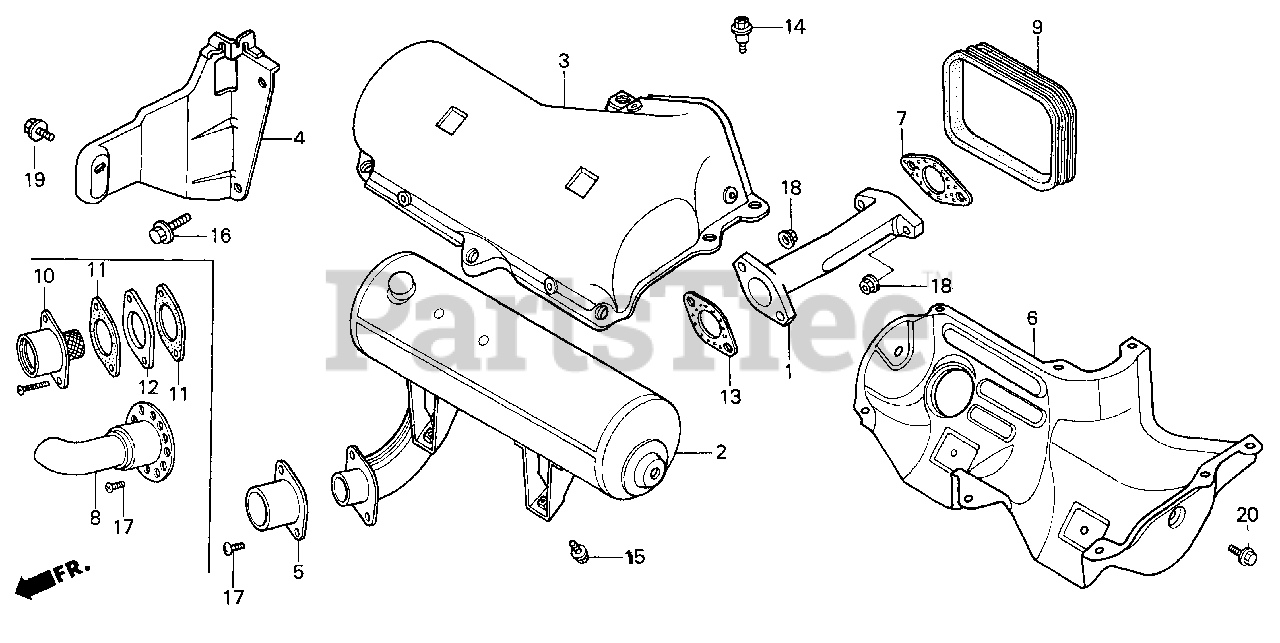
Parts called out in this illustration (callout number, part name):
3	PROTECTOR ASSY., MUFFLER (UPPER)
4	BRACKET, MUFFLER
5	PROTECTOR, TAIL PIPE
6	PROTECTOR ASSY., MUFFLER (LOWER)
7	GASKET, EX. PIPE
8	DEFLECTOR, MUFFLER
9	SEAL, MUFFLER PROTECTOR
10	ARRESTER, SPARK
11	GASKET, SPARK ARRESTER (NOT AVAILABLE)
12	SPACER, SPARK ARRESTER
13	GASKET, MUFFLER
14	BOLT, FLANGE (6X12)
15	BOLT, FLANGE (6X8)
16	BOLT, FLANGE (8X16)
17	SCREW, PAN (5X8)
18	NUT, FLANGE (8MM)
19	BOLT, FLANGE (8X14)
20	BOLT, FLANGE (6X12)
